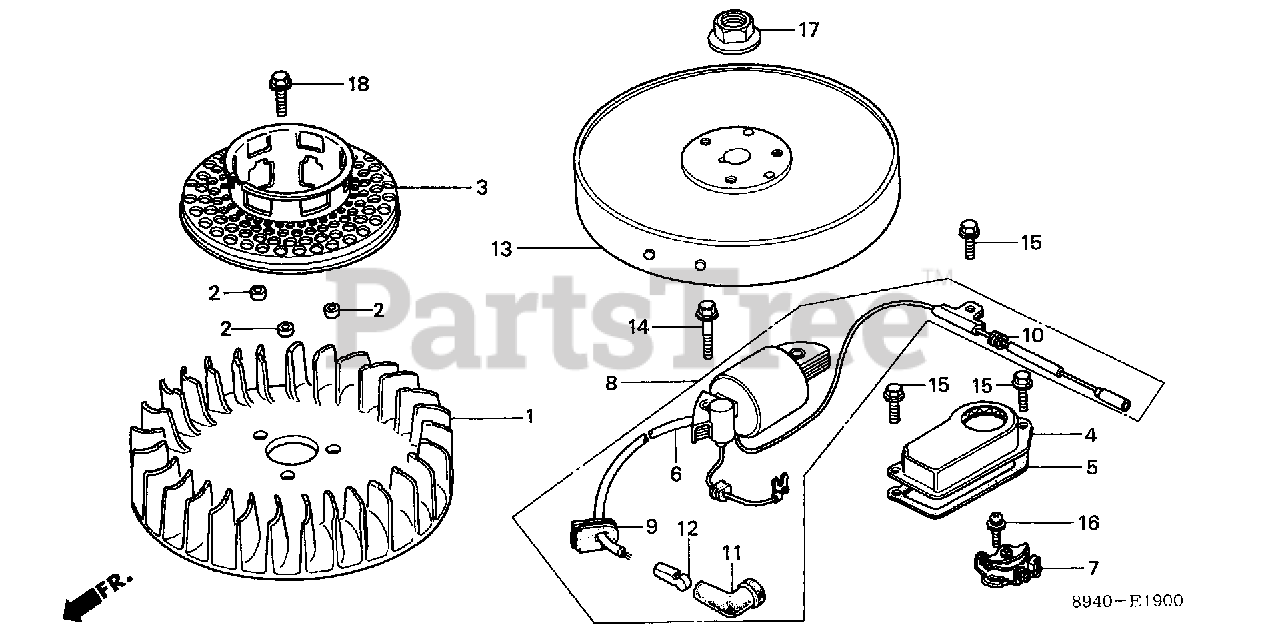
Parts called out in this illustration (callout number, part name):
1	FAN, COOLING
2	COLLAR, FAN
3	PULLEY, STARTER
4	COVER, POINTS
5	GASKET, POINT COVER
6	CONDENSER
7	POINTS ASSY.
8	COIL ASSY., IGNITION
8	COIL ASSY., IGNITION (NOT AVAILABLE)
9	GROMMET, WIRE
10	GROMMET, PRIMARY WIRE
11	CAP, IGNITION (TOYO)
12	TERMINAL, PLUG
14	BOLT, FLANGE (6X32)
15	BOLT, FLANGE (5X10)
16	SCREW-WASHER (5X12)
17	NUT, SPECIAL (14MM)
18	BOLT, FLANGE (6X16)
